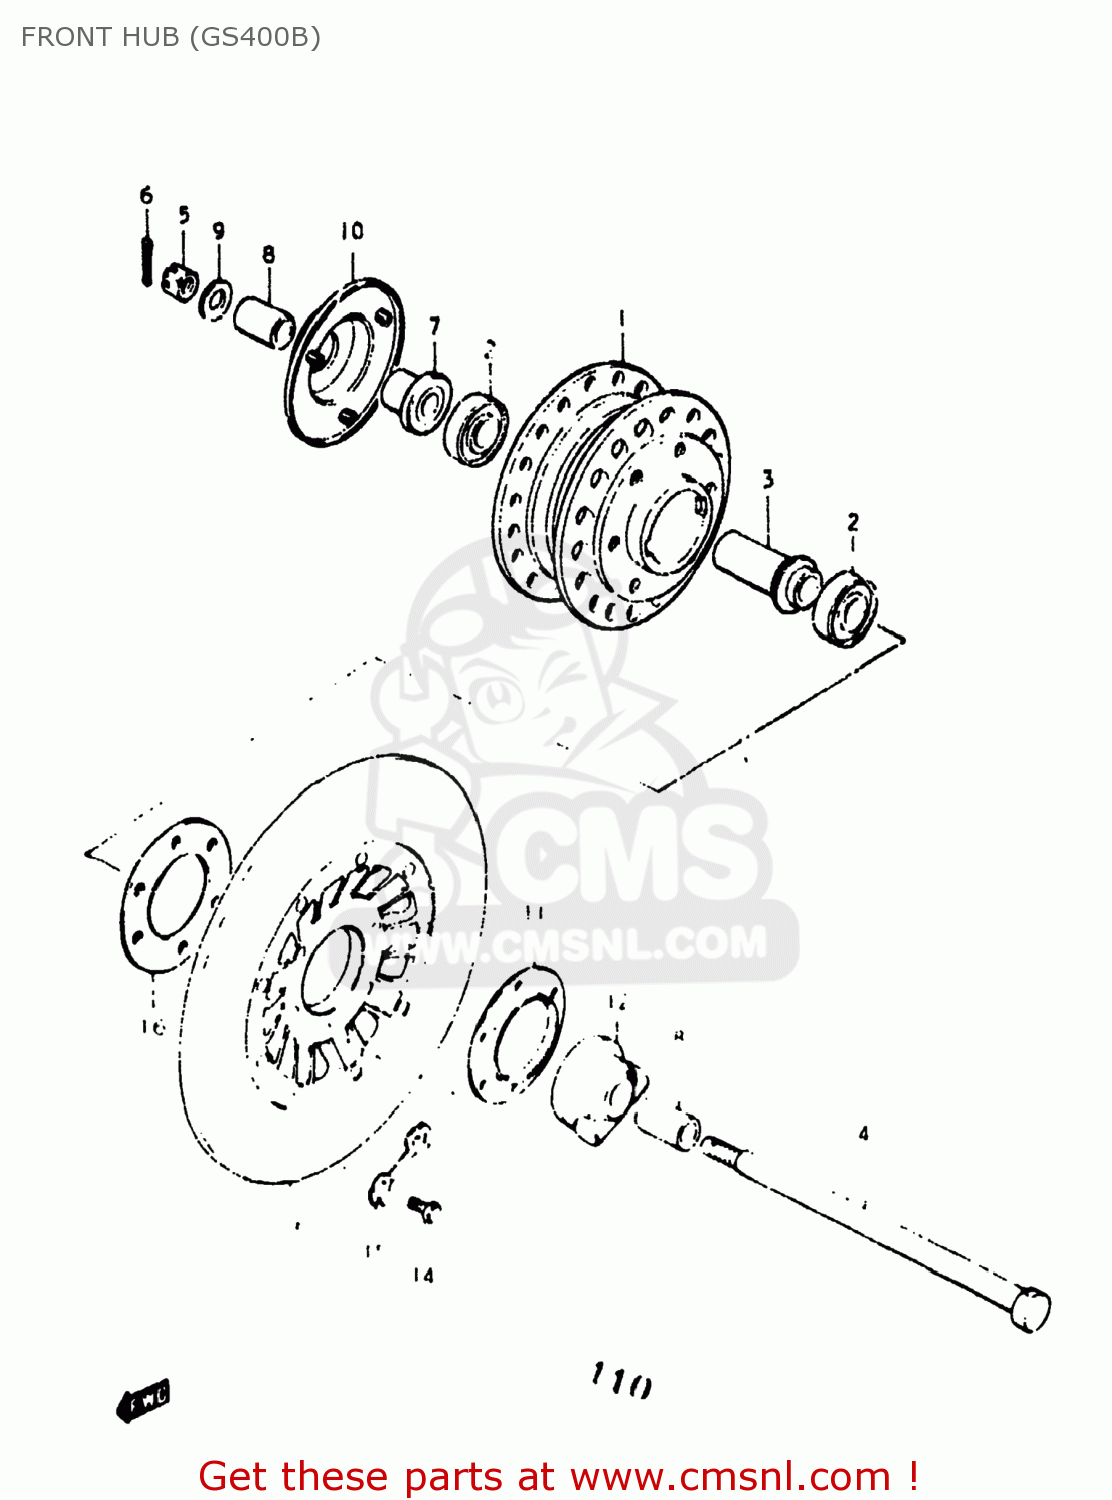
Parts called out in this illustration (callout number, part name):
1	CASTING WHEEL,FRONT
2	BEARING
3	SPACER,FR HUB BEARING
4	AXLE,FRONT
5	NUT 12MM
6	COTTER PIN
7	SPACER,FRONT AXLE,RIGHT
8	SPACER(15X22X30)
9	WASHER
10	COVER,FR HUB,R
11	DUST SEAL
12	BOX ASSY,SPEEDOMETER GEAR
13	DISC,BRAKE
14	BOLT(8X30)
15	WASHER
16	SHIM,BRAKE DISC
